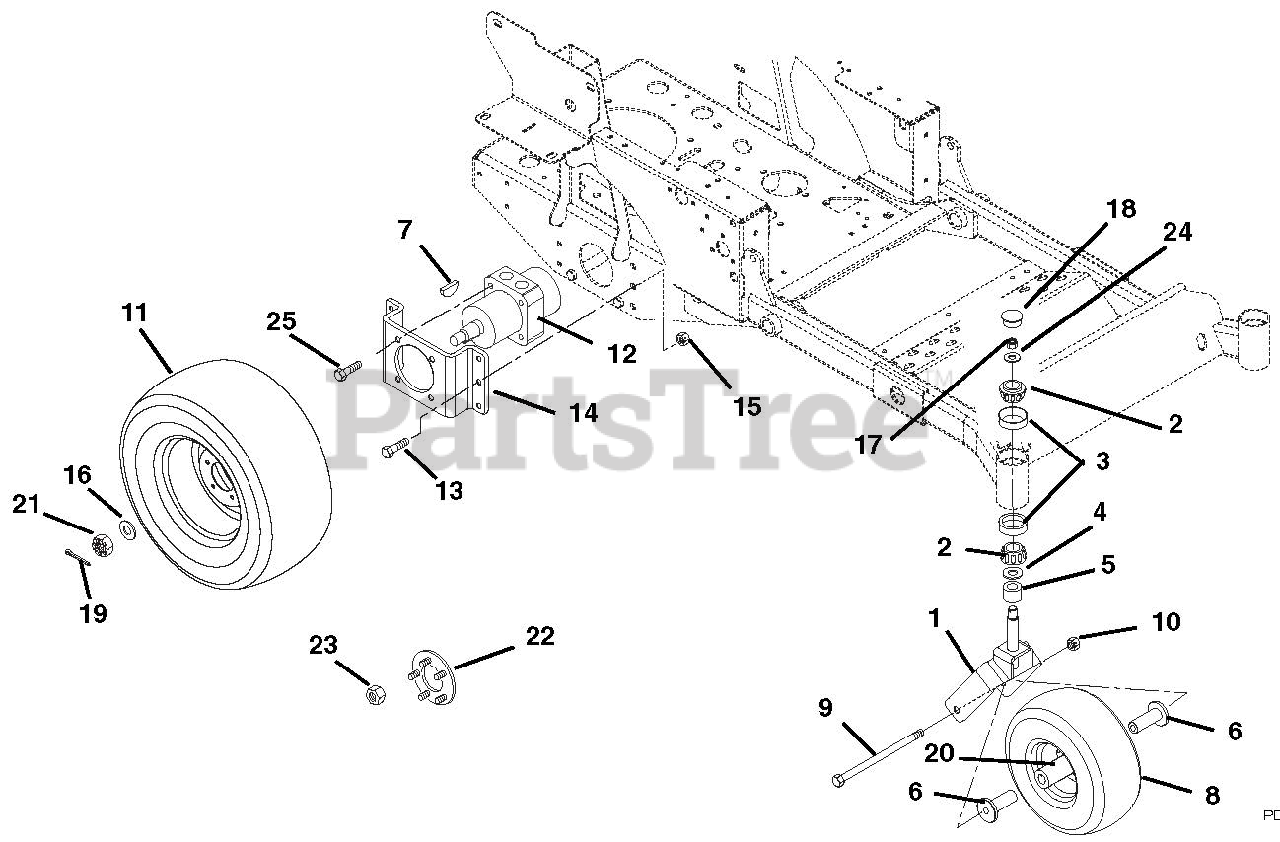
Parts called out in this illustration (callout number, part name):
1	Weldment, Front Fork
2	Bearing, Cone with Grease, 1.0 x .58
3	Bearing, Cup 1.980 x .420
4	Bearing Seal 1.5 x 2 x .18
5	Spacer, PM, 1.03 I.D. x 1.5 O.D. x .375
6	Spacer, Wheel
7	Key, Woodruff .31 x 1.00
8	Tire/Wheel Assembly, 13 x 5.00-6
8	Tire, 13 x 5.00-6
9	Bolt, Hex .50-13 x 7.50 Grade 5
10	Nut, Nyloc Flange .50-13
11	Tire/Wheel Assembly, 21 x 7.00-10
11	Tire, 21 x 7.00-10
11	Tire/Wheel Assembly, 20 x 10.00-10
11	Tire, 20 x 10.00-10
12	Motor, Hydraulic Wheel
13	Bolt, Hex .38-16 x 1.00 Grade 5
14	Bracket, Wheel Motor
15	Nut, Nyloc Flange 3/8-16
16	Washer, Flat Steel .755 x 1.375 x .062
17	Nut, Center Lock Jam .75-16
18	Cap, Dust
19	Pin-Cotter .09 x 1.25 Extended Prong Square Cut
20	Bearing, 25MM I.D. x 52MM OD x 15MM
21	Nut, Hex .75-20
22	Assembly, Service Hub with Studs
22	Assembly, Service Hub with .50 Studs
23	Wheel Nut .50-20
23	Wheel Nut .437-20
24	Washer, Flat, Steel .880 x 1.250 x .062
25	Bolt, Hex .38-16 x 1.00 Grade 8 Epoxy 30
